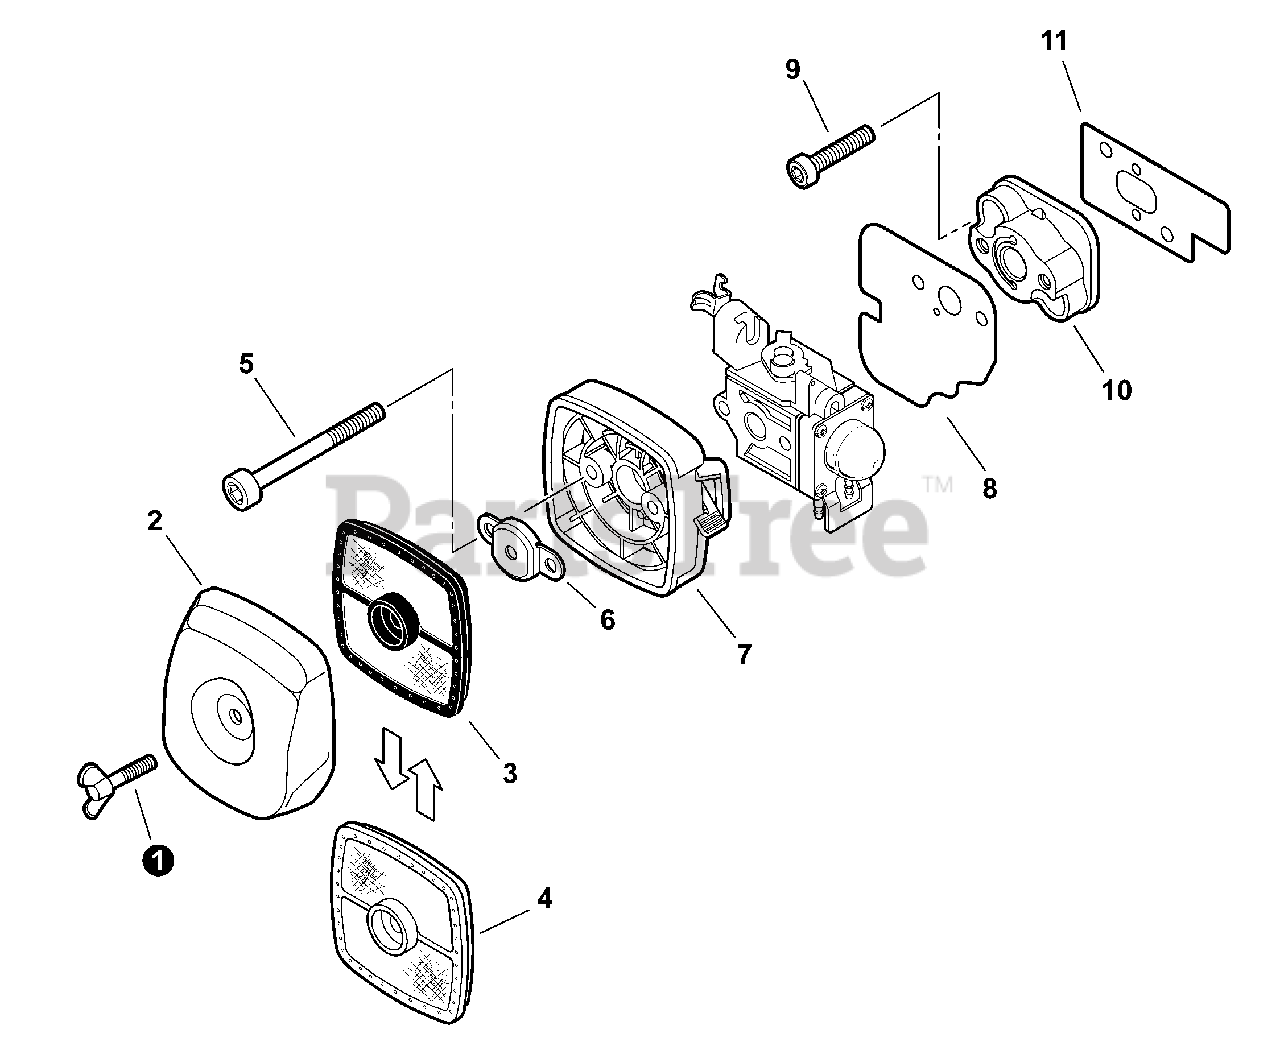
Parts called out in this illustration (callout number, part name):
1	BOLT, WING 5×20
2	COVER, AIR FILTER - BLACK
3	FILTER, AIR - DOUBLE LAYER
4	FILTER, AIR - SINGLE LAYER
5	BOLT, TORX 5×65
6	PLATE, PREVENT
7	CASE, AIR FILTER - BLACK
8	GASKET, INTAKE
9	BOLT, TORX 5×25
10	INSULATOR, INTAKE
11	GASKET, INTAKE
